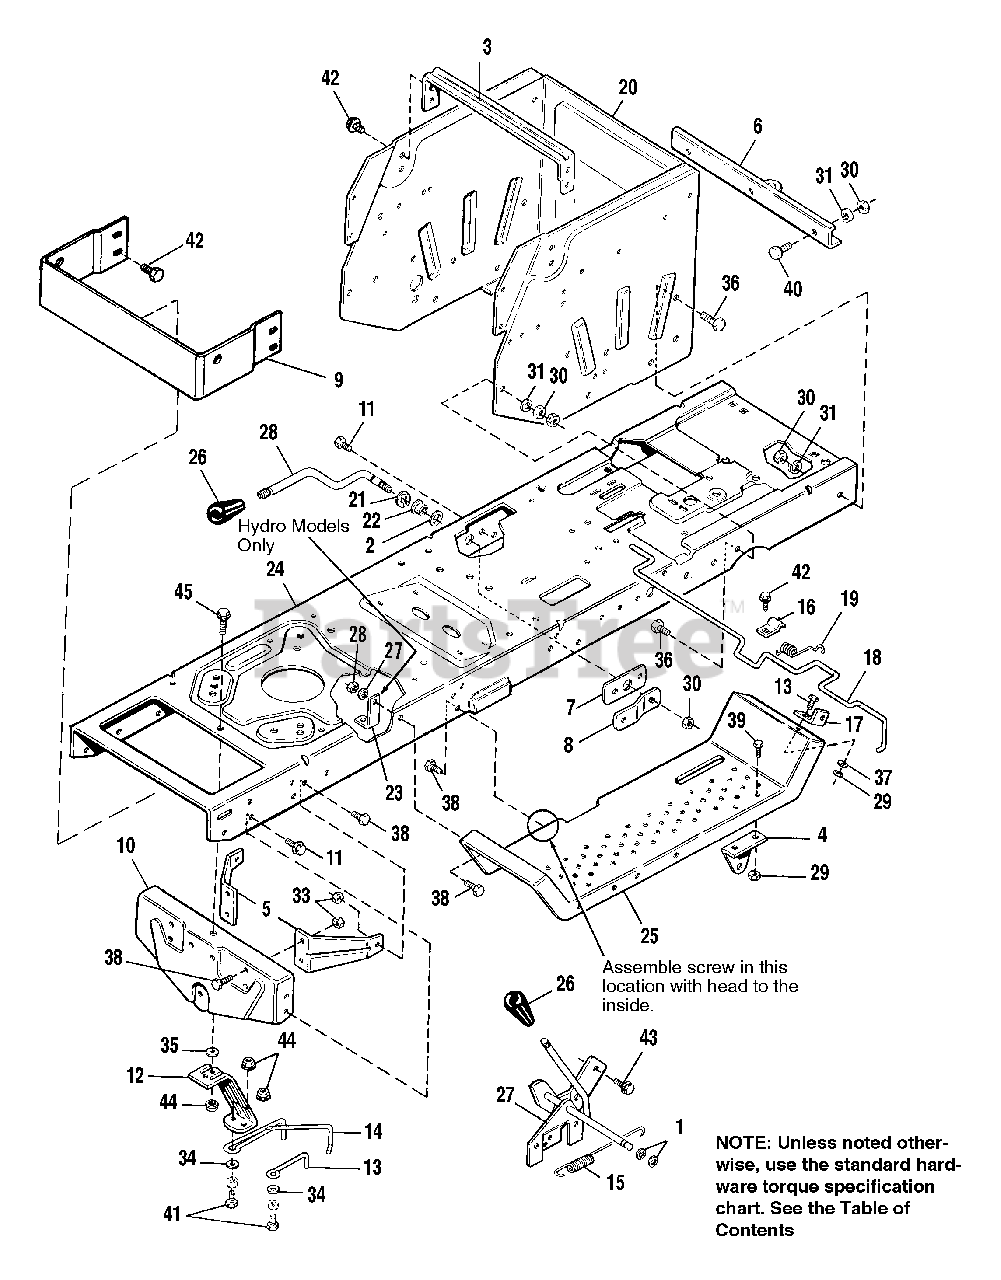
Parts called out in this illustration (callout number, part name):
1	RING, Retaining
3	BRACE, Seat
4	SUPPORT, Clutch
5	BRACE, Axle Support
6	BAR, Draw
7	BAR, Support
8	ARM, Support
9	SUPPORT, Hood
10	SUPPORT, Axle
11	SCREW, Taptite, 5/16-18 x 3/4
15	SPRING, Extension
17	BRACKET, Seat Latch
18	ROD, Latch
19	SPRING, Torsion
20	SUPPORT, Axle Wrapper
21	KLIPRING, 1/2
23	BRACKET, Spring
26	KNOB, Handle
27	HANDLE ASSY., PTO Clutch
28	HANDLE, Lift
29	NUT, Hex, 1/4-20
30	NUT, Hex, 3/8-16
31	LOCKWASHER, 3/8
33	NUT, Hex, Full, 5/16-18
34	WASHER, 11/32
35	WASHER, Plain, 11/32-1 x 10 Ga.
36	CAPSCREW, Hex, 3/8-16 x 1
37	WASHER
38	CAPSCREW, Hex, 5/16-18 x 3/4
39	CAPSCREW, Hex, 1/4-20 x 5/8
40	CAPSCREW, Hex, 3/8-16 x 3/4
41	CAPSCREW, Hex, 5/16-18 x 7/8
42	SCREW, Taptite, 5/16-18 x 1/2
43	SCREW
44	LOCKNUT, Hex, Flange Whiz, 5/16-18
45	CAPSCREW, Hex Flange Hd., 5/16-18 x 1-1/4
